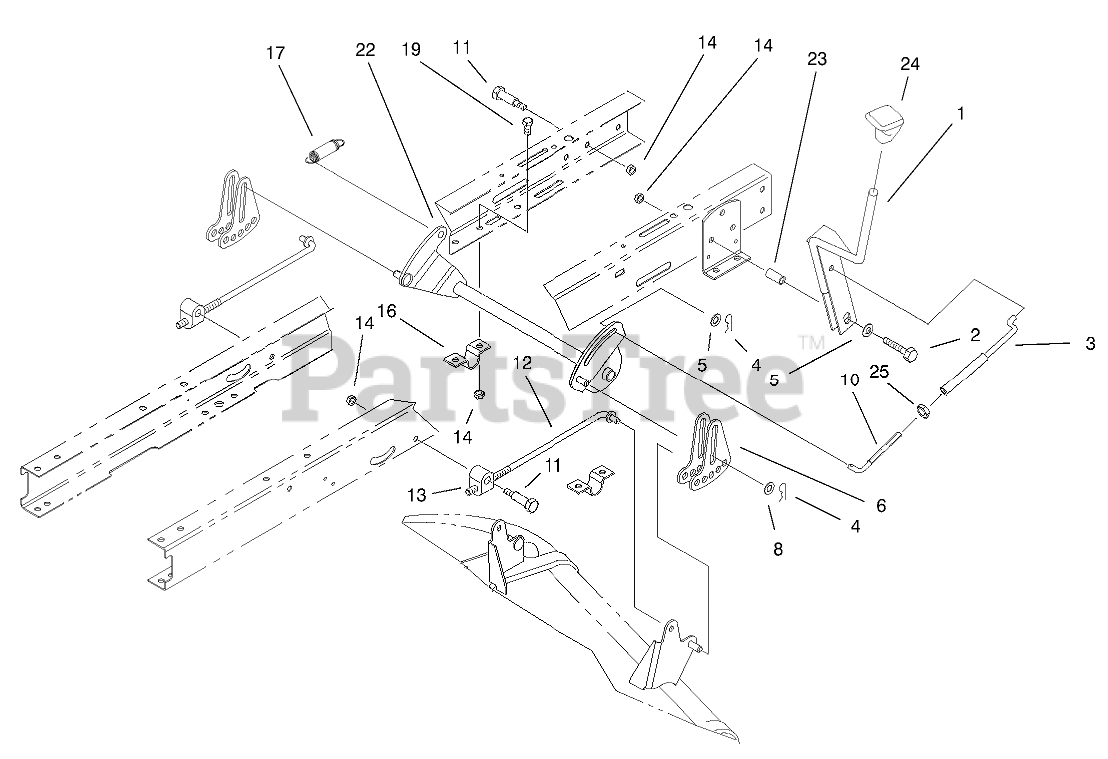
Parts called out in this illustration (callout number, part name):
1	HOC LEVER ASM
2	SCREW-HH
4	PIN-COTTER
5	WASHER-FLAT
6	LINK-ADJUSTING, HOC
8	WASHER-HARDENED
10	LINK-HOC
11	SCREW-SHOULDER, HH
12	ROD-HANGER, REAR
13	TRUNNION-HOC
14	NUT-LOCK, NI
16	CLAMP-PIVOT, HOC
17	SPRING-EXTENSION
19	SCREW-HH
22	PIVOT-HOC
23	SPACER
24	KNOB-SHIFT
25	NUT-JAM
